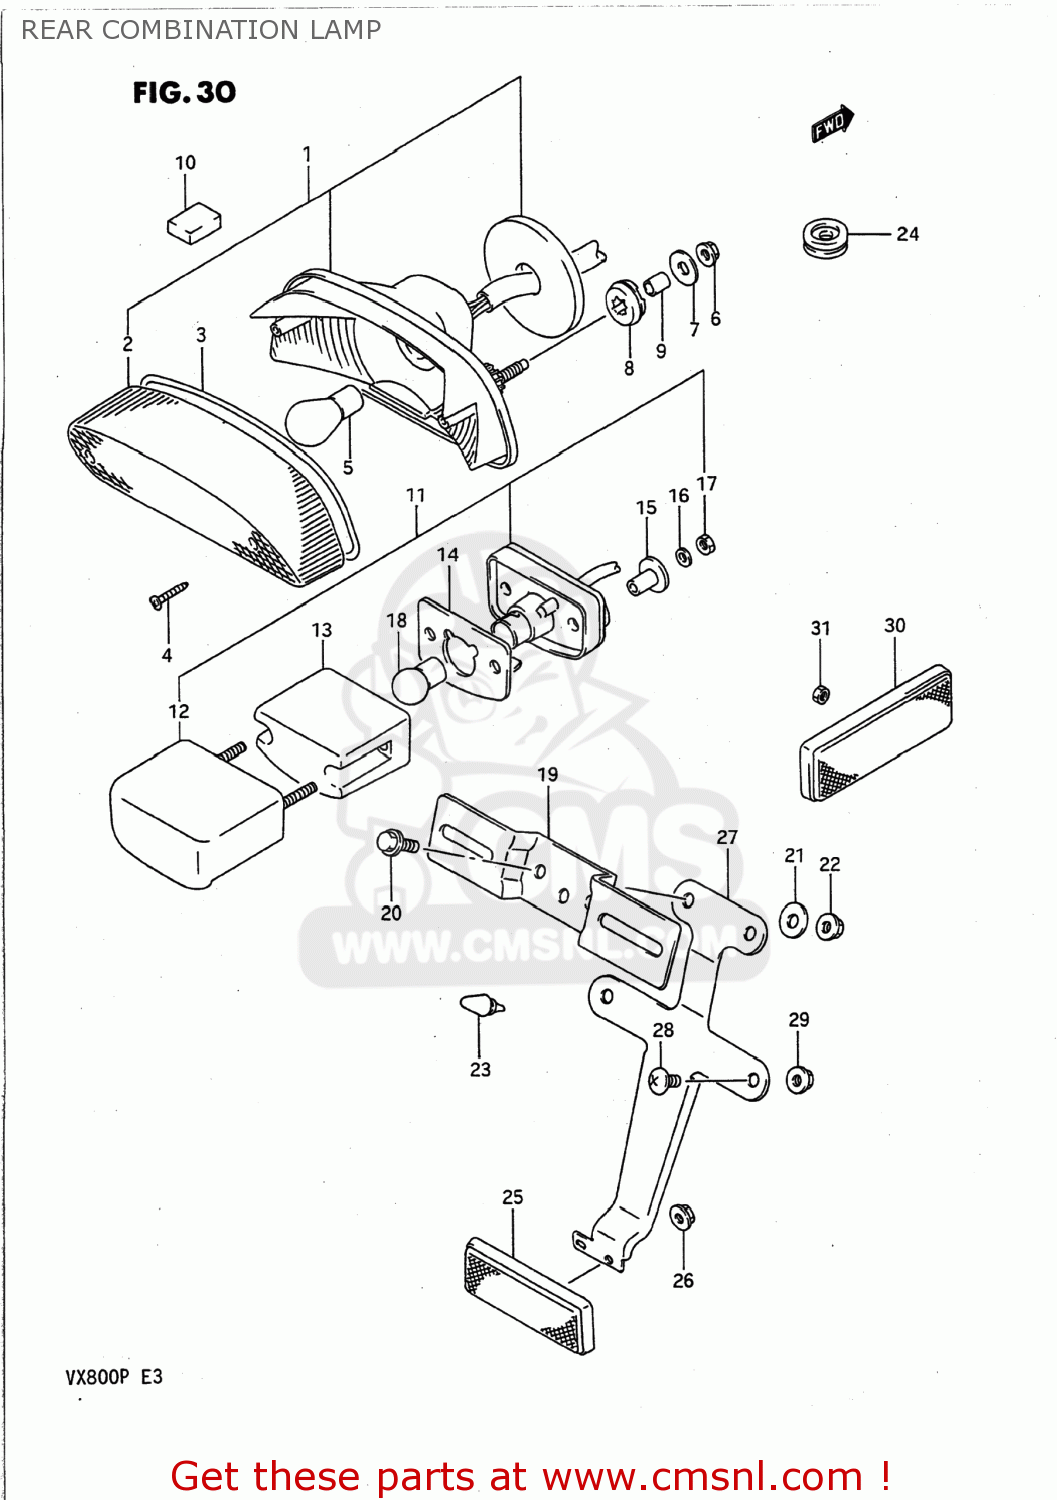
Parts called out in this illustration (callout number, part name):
1	LAMP ASSEMBLY,REAR COMBINATION
2	LENS
3	GASKET (NAS)
4	SCREW
5	BULB(12V21/5W)
6	NUT
7	WASHER
8	CUSHION
9	SPACER (6.1X9X10)
10	CUSHION,REAR COMBINATION LAMP
11	LAMP ASSEMBLY,LICENSE
12	COVER,LICENSE LAMP
13	LENS
14	GASKET,LICENSE LAMP (NAS)
15	SPACER
16	WASHER,LOCK 4M
17	NUT
18	BULB
19	BRACKET,LICENSE PLATE
20	BOLT
21	WASHER,COVER,FRONT
22	NUT
23	CUSHION
24	GROMMET
25	REFLECTOR ASSEMBLY,REAR
26	NUT 5MM
27	BRACKET,RR RR
28	SCREW 6X12
29	NUT
30	REFLECTOR ASSEMBLY,REAR
31	NUT 5MM
